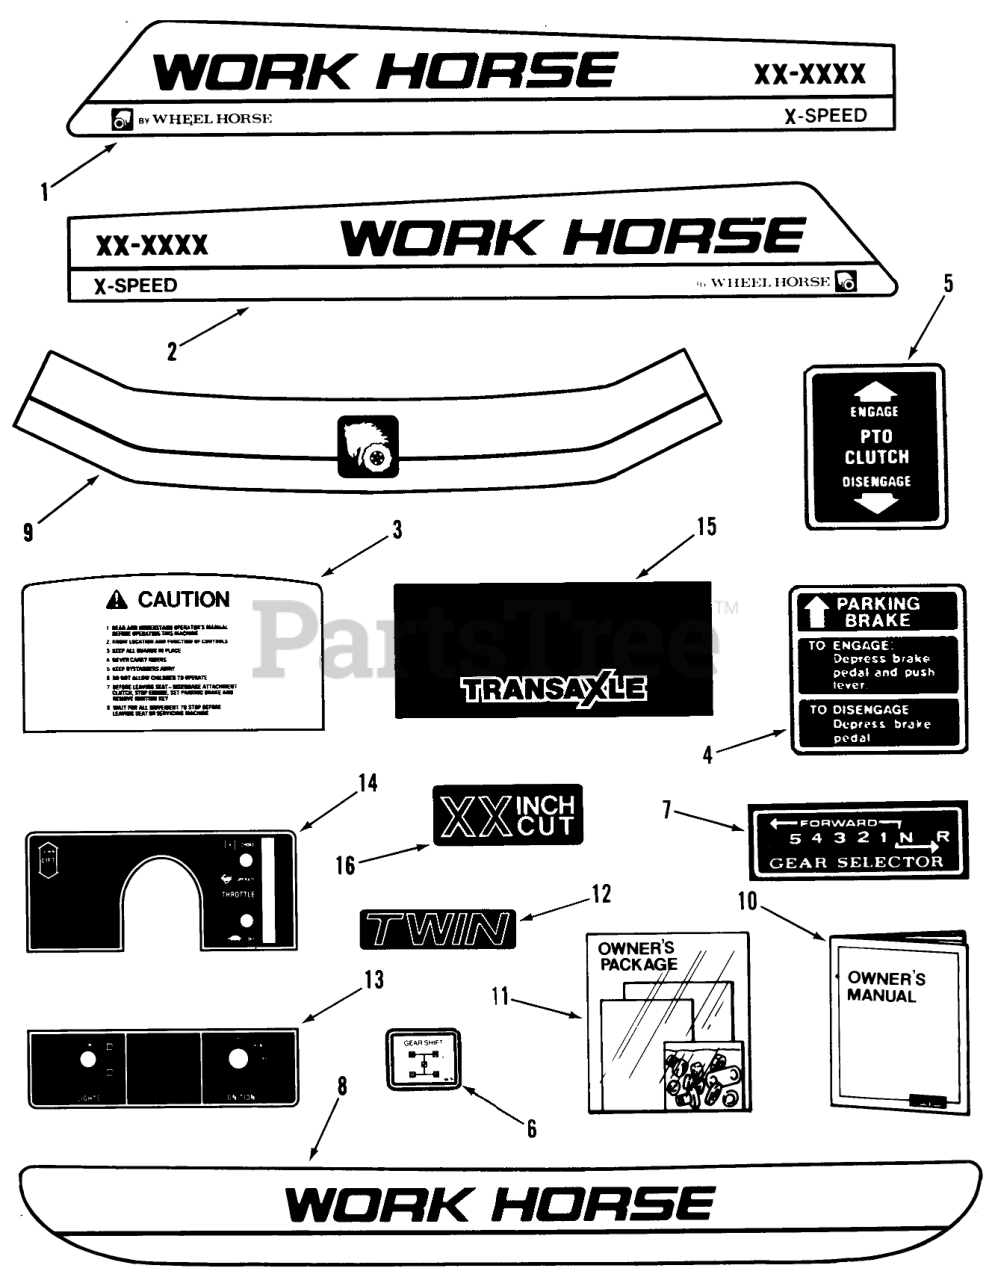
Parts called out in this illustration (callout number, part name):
1	Decal-Hood RH LT-1137 Only
1	Decal-Hood RH LT-1637 Only
1	Decal-Hood RH LT-1642 Only
1	Decal-Hood RH LT-832 Only
1	Decal-Hood RH LT-1032 Only
2	Decal-Hood LH LT-1137 Only
2	Decal-Hood LH LT-1637 Only
2	Decal-Hood LH LT-1642 Only
2	LH HOOD DECAL
2	Decal-Hood LH LT-1032 Only
3	DECAL - CAUTION
4	Decal Parking Brake
5	DECAL-PTO CLUTCH
6	DECAL-SHIFT
7	DECAL-SHIFT
8	Decal Rear
9	DECAL - HOOD FRONT
10	Owner-s Manual
11	New Tractor Loose Parts Package LT-1137 Only
11	New Tractor Loose Parts Package LT-1637, LT-1642 Only
11	New Tractor Loose Parts Package LT-832 Only
11	New Tractor Loose Parts Package LT-1032 Only
12	Decal-Engine LT-1600 Only
13	DECAL-BACK PLATE-SWI
14	DECAL - LOWER DASH
15	DECAL - TRANSAXLE
16	Decal-37 in. Mower
16	Decal 42 in. Mower
16	Decal-Mower
